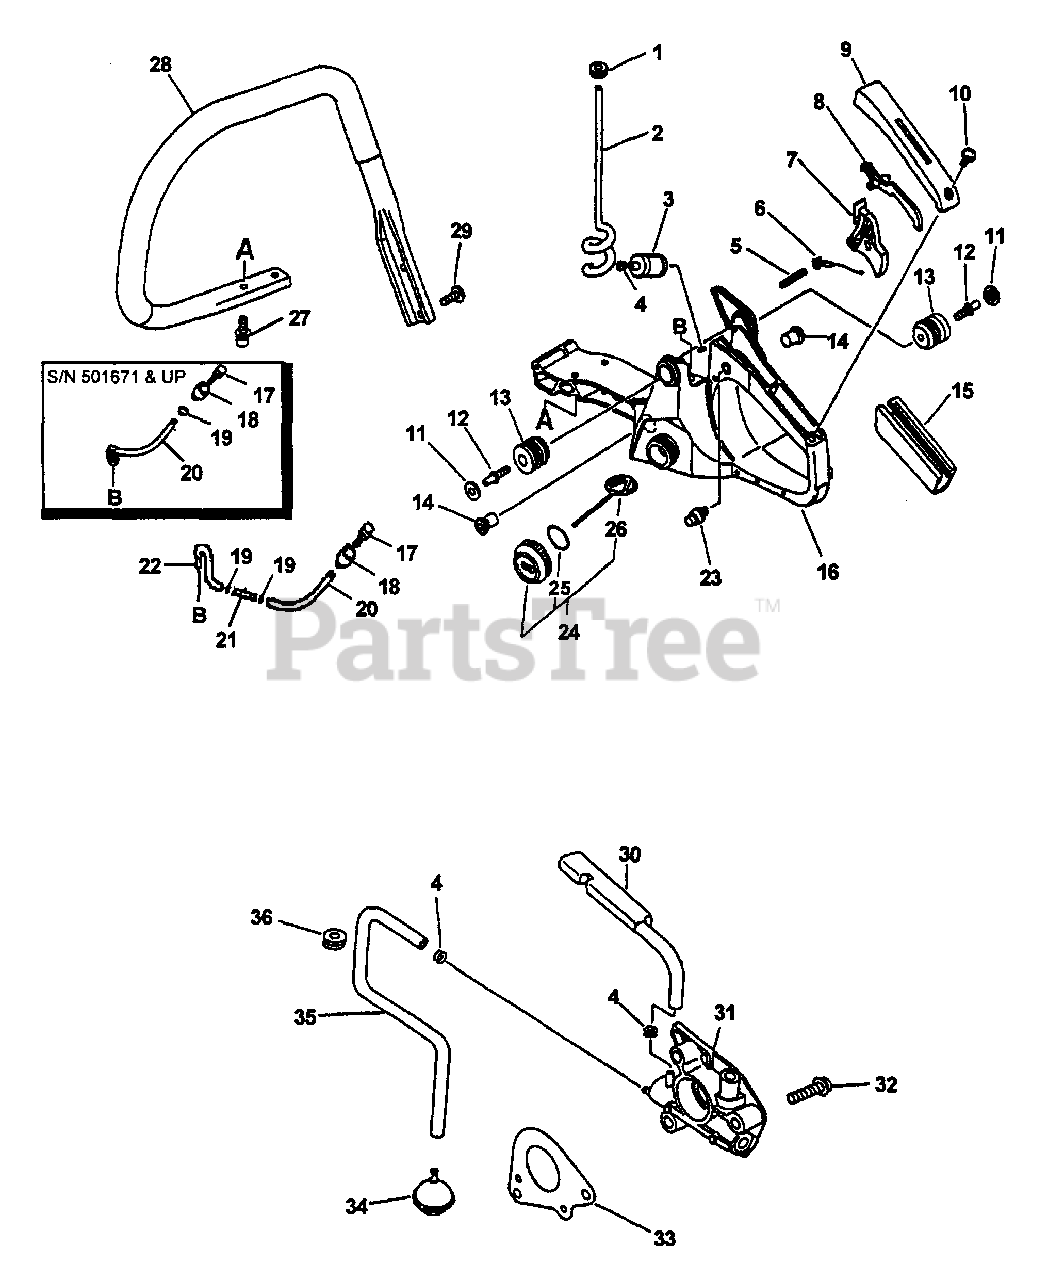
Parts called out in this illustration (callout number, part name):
2	PIPE, FUEL 3×6×165
3	FILTER, FUEL
4	CLIP Ø6.5 MM
5	PIN, SPRING 4×30
6	SPRING, THROTTLE RETURN
7	TRIGGER, THROTTLE
8	LEVER, THROTTLE LOCKOUT
9	COVER, HANDLE
10	SCREW 4×14
11	CAP, CUSHION
13	CUSHION 5
14	CUSHION 5
15	GRIP, HANDLE
16	REAR HANDLE KIT
17	VENT ASSY
18	HOLDER, VENT
19	CLIP 5.5
19	CLIP Ø6.5 MM
20	PIPE, FUEL 3×5×100
20	PIPE, VENT - GROMMET
21	CONNECTOR
22	PIPE
23	LATCH, THROTTLE
24	CAP ASSY, FUEL
25	O-RING 22
26	CONNECTOR, CAP L= 60 MM
27	SCREW 5×16
28	HANDLE, FRONT
29	SCREW, TAPPING
30	PIPE, OIL OUTLET
31	AUTO-OILER ASSY
32	SCREW 4×16
33	PLATE, SEAL
34	FILTER, OIL
35	PIPE, OIL
